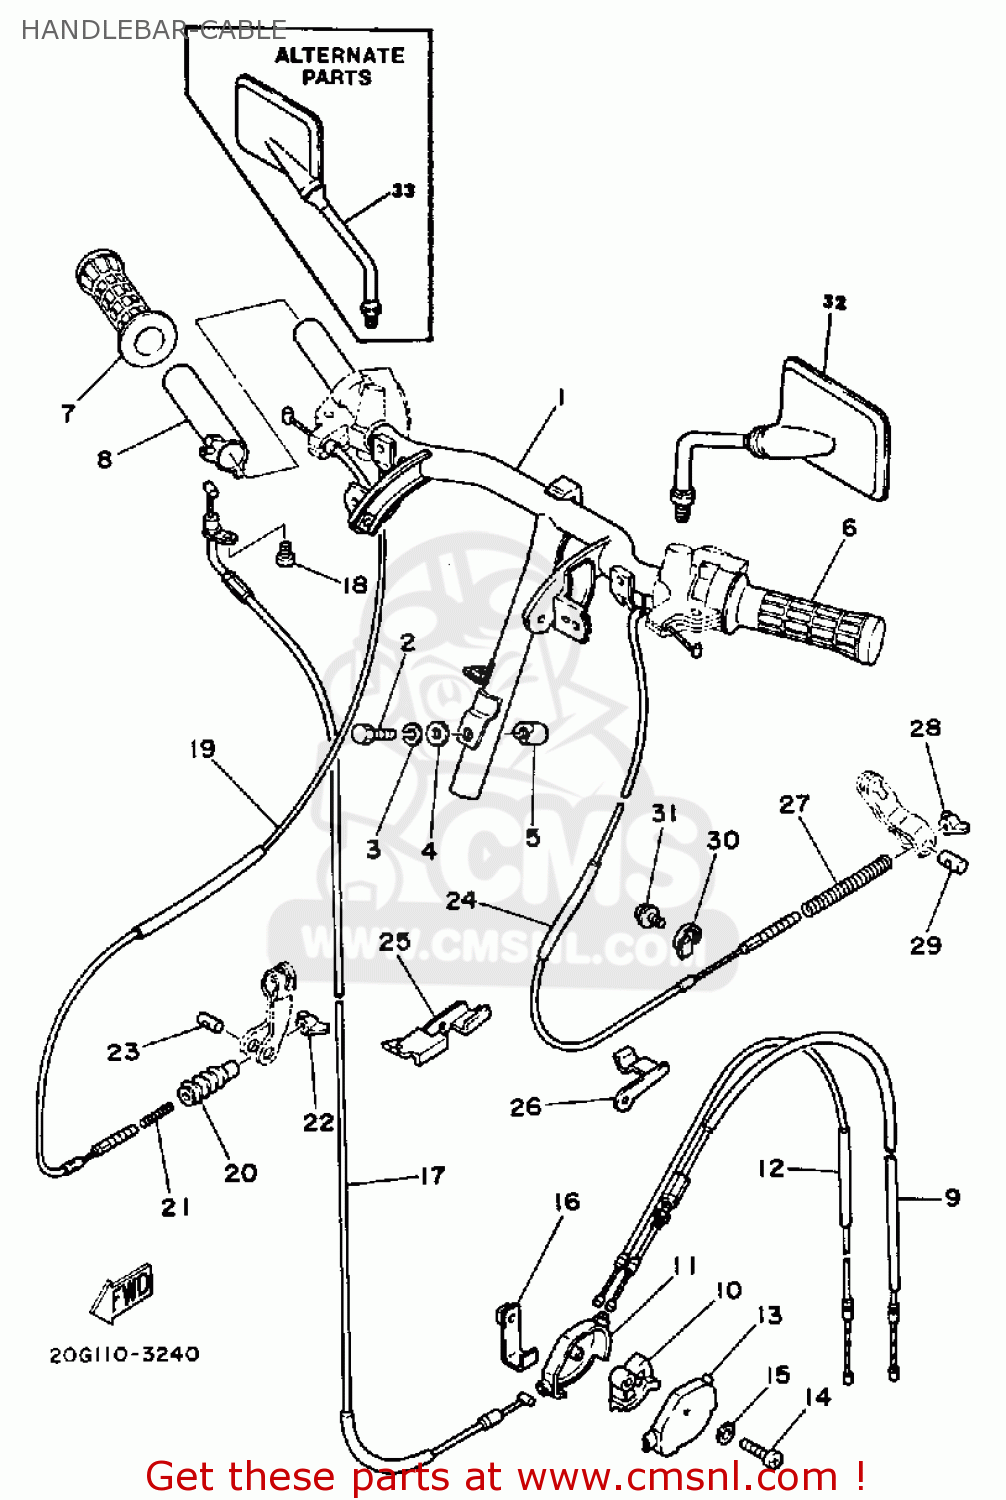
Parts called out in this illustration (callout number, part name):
1	HANDLE COMP.
2	BOLT (2T4)
3	YBS67-8 WASHER, SPRING
4	WASHER
5	NUT (5M1)
6	GRIP (L.H)
7	GRIP (R.H)
8	TUBE, THROTTLE GUIDE
9	CABLE, PUMP
10	PIECE, CONNECTING
11	CONNECTOR, CABLE
12	CABLE, THROTTLE 2
13	CAP, CABLE CONNECTOR
14	SCREW, PAN HEAD
15	WASHER, PLATE (517)
16	WASHER
17	CABLE, THROTTLE 1
18	SCREW,PAN HEAD (646)
19	CABLE, BRAKE
20	BOOT, CABLE
21	SPRING, COMPRESSION (2T4)
22	NUT (25K)
23	PIN
24	CABLE, BRAKE
25	CLAMP (14T)
26	CLAMP (14T)
27	SPRING, COMPRESSION (14T)
28	NUT (25K)
29	PIN
30	HOLDER
31	BOLT (3L7)
32	REAR VIEW MIRROR ASSY(LEFT)
33	REAR VIEW MIRROR ASSY(RIGHT)
